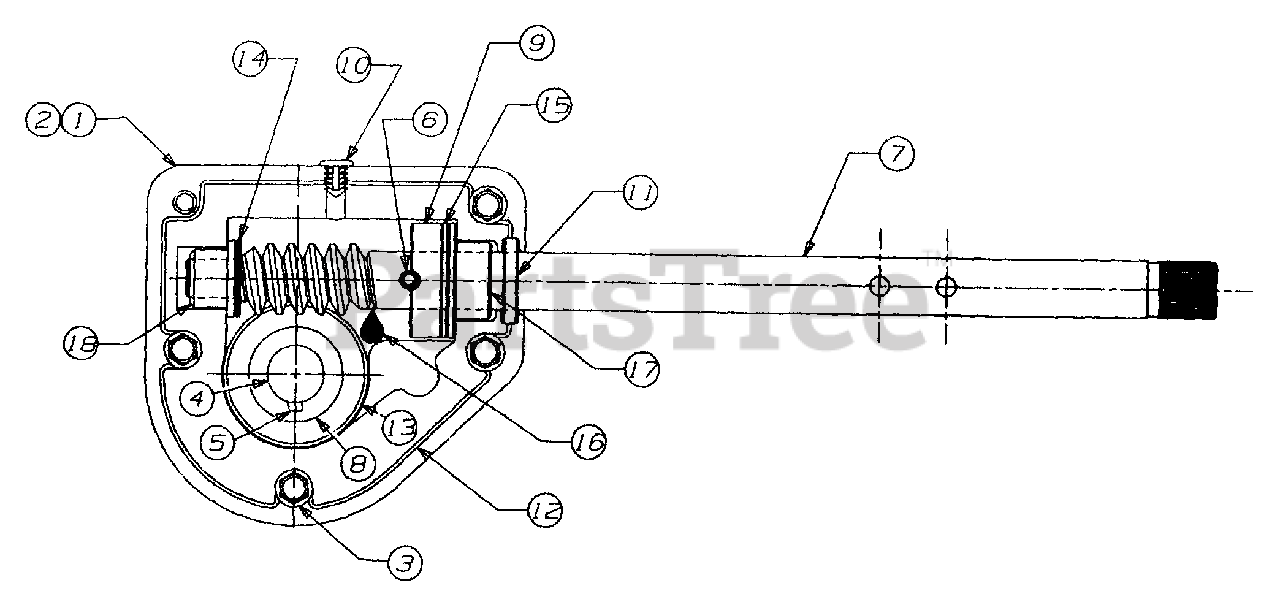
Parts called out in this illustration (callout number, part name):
1	Housing - R.H.
2	Housing - L.H.
3	Screw
4	Axle, Spiral 28"
4	Axle, Spiral 24"
5	Key, Hi-Pro
6	Pin, Spiral
7	Worm, Shaft
8	Gear, Worm
9	Collar, Thrust
11	Seal, Oil
12	Loctite 5699, Ultra
13	Washer
14	Washer
15	Washer
16	Grease
17	Bearing Flange
18	Bearing Flange
